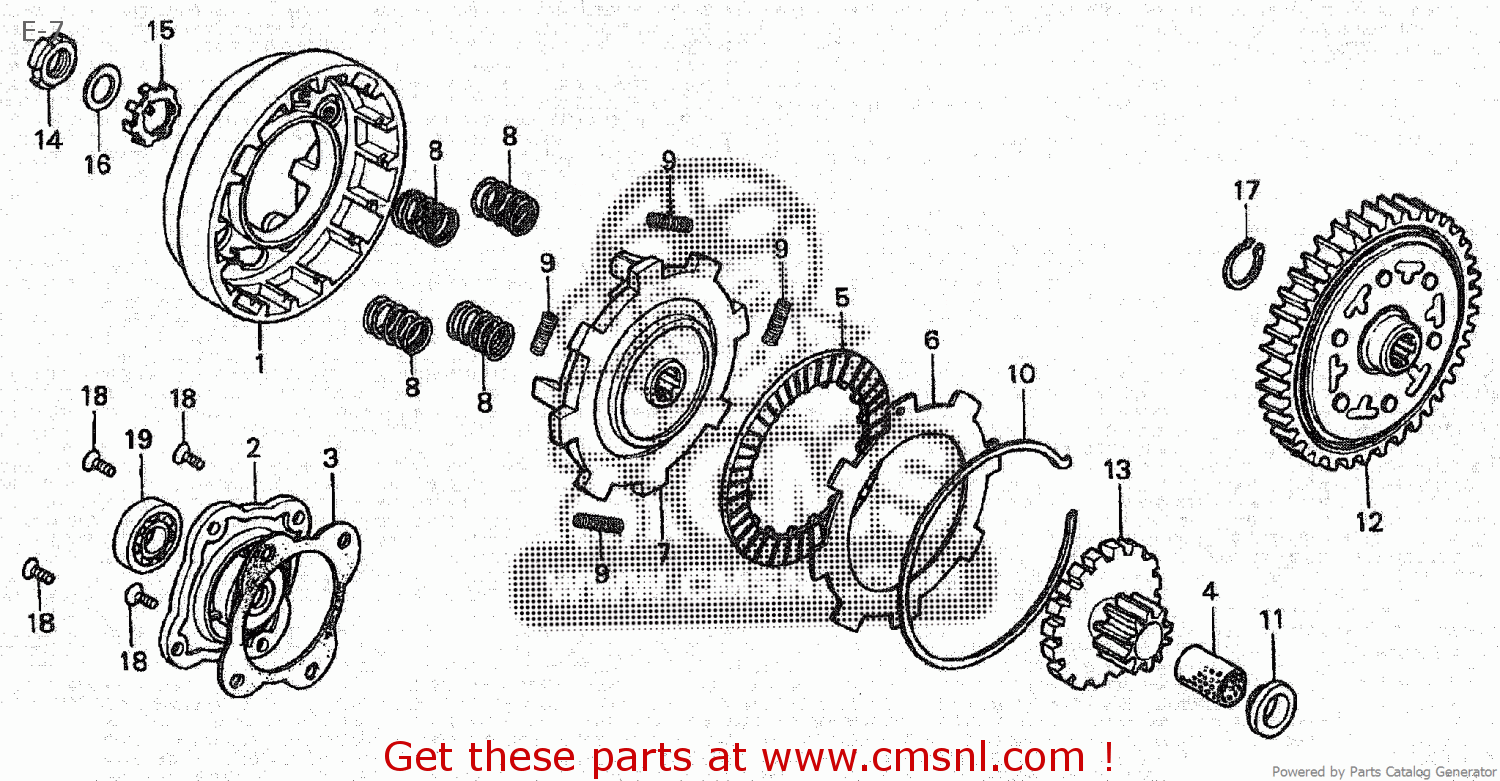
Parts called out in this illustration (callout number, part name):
1	OUTER CLUTCH
2	COVER,CLUTCH OUT
3	GASKET,CLUTCH OUT (NAS)
4	GUIDE,CLUH.CENTER
5	DISK,CLUTCH FRICT (NAS)
6	PLATE C, CLUTCH
7	PLATE,DRIVE
8	SPRING, CLUTCH
9	SPRING, CLUTCH
10	SET RING,101.5M/M
11	COLLER,17MM
12	GEAR,PRIM.DRIVEN
13	GEAR,PRIMARY DRIV
14	NUT LOCK 14M/M
15	WASHER,LOCK 14MM
16	WASHER B,LOCK
17	CIRCLIP, 17M/M
18	SCREW,FLAT,5X10
19	B/BRG RAD N/COM
